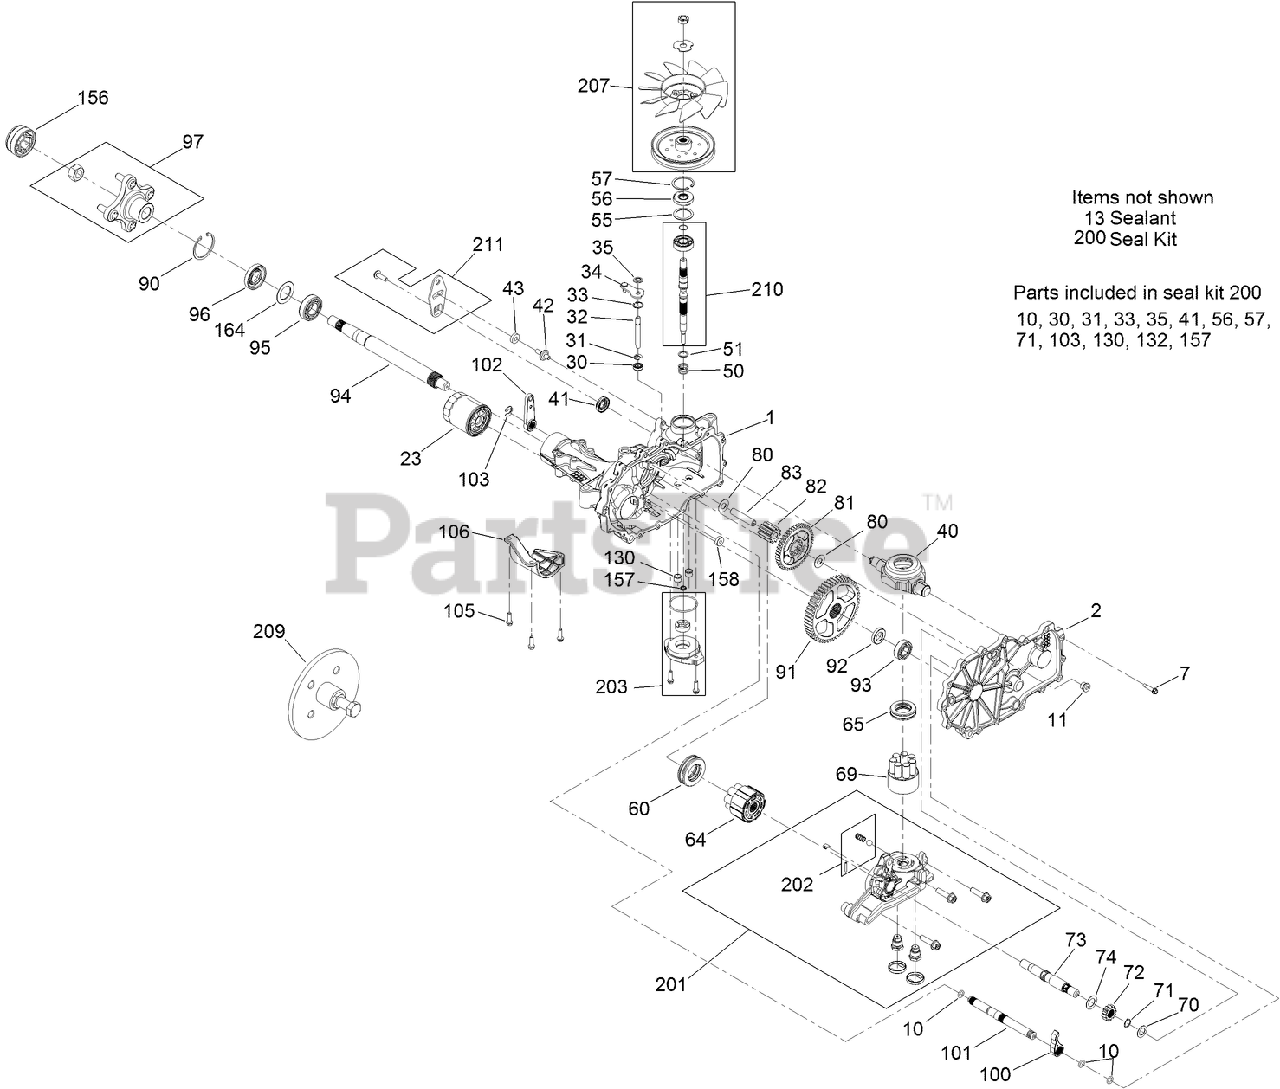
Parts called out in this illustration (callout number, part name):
1	LH MAIN HOUSING KIT
2	LH SIDE COVER KIT
7	SCREW-HHF
10	O-RING
11	PLUG-THREAD, STRAIGHT
23	ELEMENT-OIL FILTER, HYD
30	SEAL-LIP
31	RING-RETAINING, EXTERNAL
32	ROD-BYPASS
33	RING-RETAINING, INTERNAL
34	ARM-BYPASS
35	RING-RETAINING, EXTERNAL
40	SWASHPLATE-TRUNNION
41	SEAL-LIP
43	PUCK-FRICTION
50	SPRING-COMPRESSION
51	WASHER
55	SPACER
56	SEAL-LIP
57	RING-RETAINING
60	Bearing-Thrust
64	MOTOR CYLINDER BLOCK KIT
65	BEARING-THRUST, PLASTIC CAGE
69	7 PISTON BLOCK ASM
70	WASHER-FLAT
71	RING-RETAINING
72	GEAR-13T
73	SHAFT-MOTOR
74	WASHER
80	WASHER
81	GEAR-46T
82	GEAR-11T
83	PIN-JACKSHAFT
90	RING-RETAINING
91	GEAR-54T
92	SPACER
93	BEARING-BALL
94	SHAFT-AXLE
95	BEARING-BALL
96	SEAL-LIP
97	HUB KIT
100	PAWL-BRAKE
101	SHAFT-BRAKE, INBOARD
102	HANDLE-BRAKE
103	RING-RETAINING, EXT
106	GUARD-FILTER, LH
130	TUBE-PUSH, O-RING
156	COVER-NUT, AXLE
157	SEAL-GEROTOR
158	MAGNET-RING
164	SPACER
201	KIT-CENTER SECTION (LH CHARGE)
202	CHARGE RELIEF KIT
203	CHARGE PUMP KIT
207	FAN AND PULLEY KIT
209	HUB PULLER KIT
210	INPUT SHAFT KIT
211	CONTROL ARM KIT
